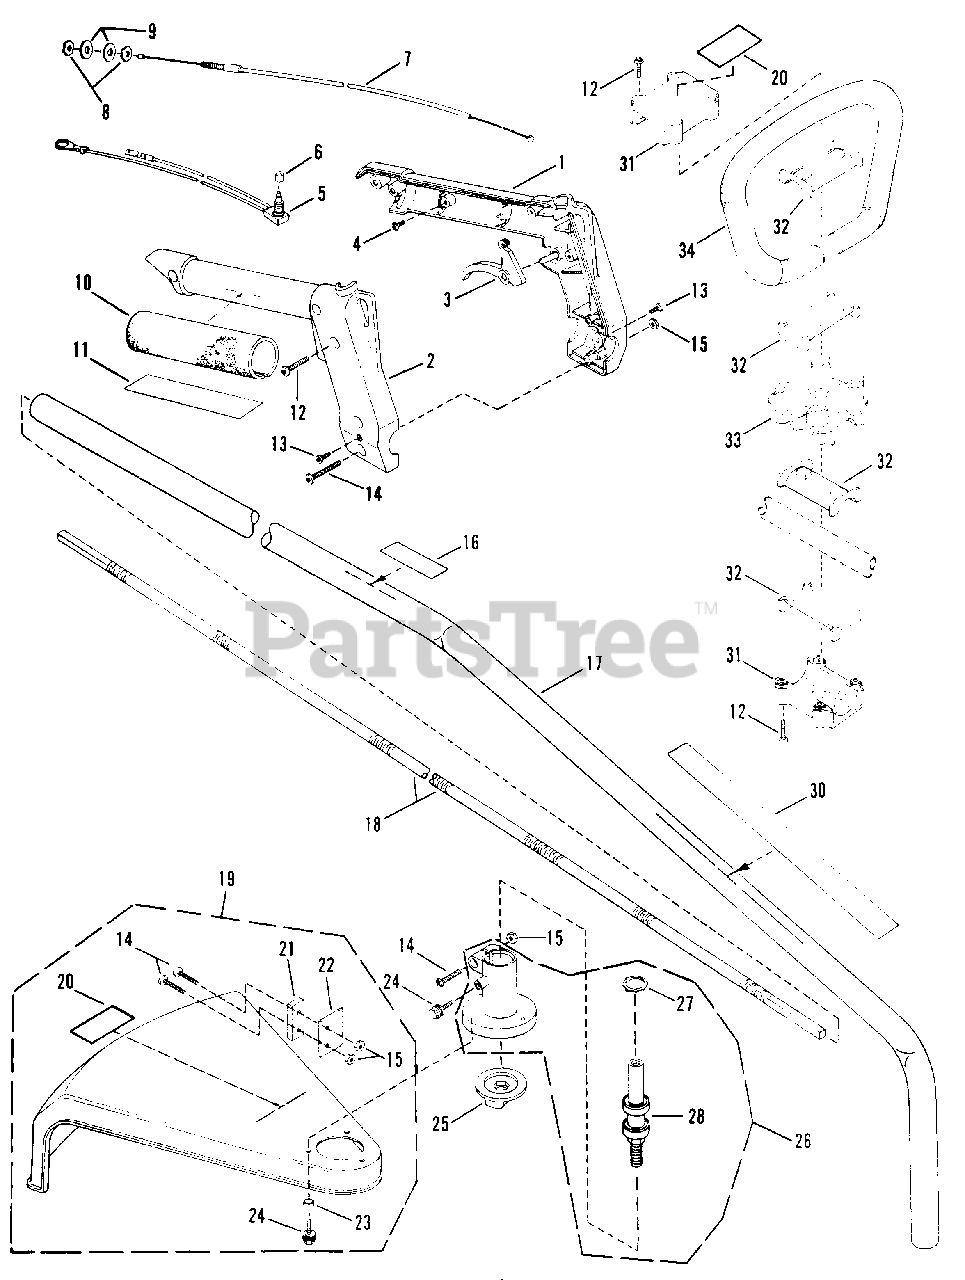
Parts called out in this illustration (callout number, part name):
1	HANDLE, Left Half
2	HANDLE, Right Half
3	TRIGGER
4	SCREW, #10-16 x 3/8"
5	SWITCH
6	CAP, Switch
7	CABLE, Throttle
8	NUT, M6 Hex
10	GRIP, Handle
11	STRIP, Adhesive
12	SCREW, #10-16 x 3/4"
13	SCREW, TORX, #6 x 5/16"
14	SCREW, #10-32 x 7/8"
15	LOCKNUT, #10-32
16	DECAL-WARNING (Eye Protection)
17	TUBE/DECAL ASSM'Y.
18	SHAFT, Flex (53.96" x .245", .2" Square Ends x 1.38")
19	SHIELD ASSM'Y. KIT
20	DECAL, Replacement Part
21	BLOCK, Line Cutter Mounting
22	CUTTER ASSM'Y., Line
24	SCREW, #10-24 x 5/8"
25	DUST SHIELD
26	BEARING HOUSING ASSM'Y.,
27	RETAINER
28	BEARING/ARBOR ASSM'Y.
30	DECAL, Model
31	HANDLE MOUNT, Cap
32	ISO-MOUNT
33	HANDLE MOUNT, Center
34	HANDLE ASSM'Y., Loop
